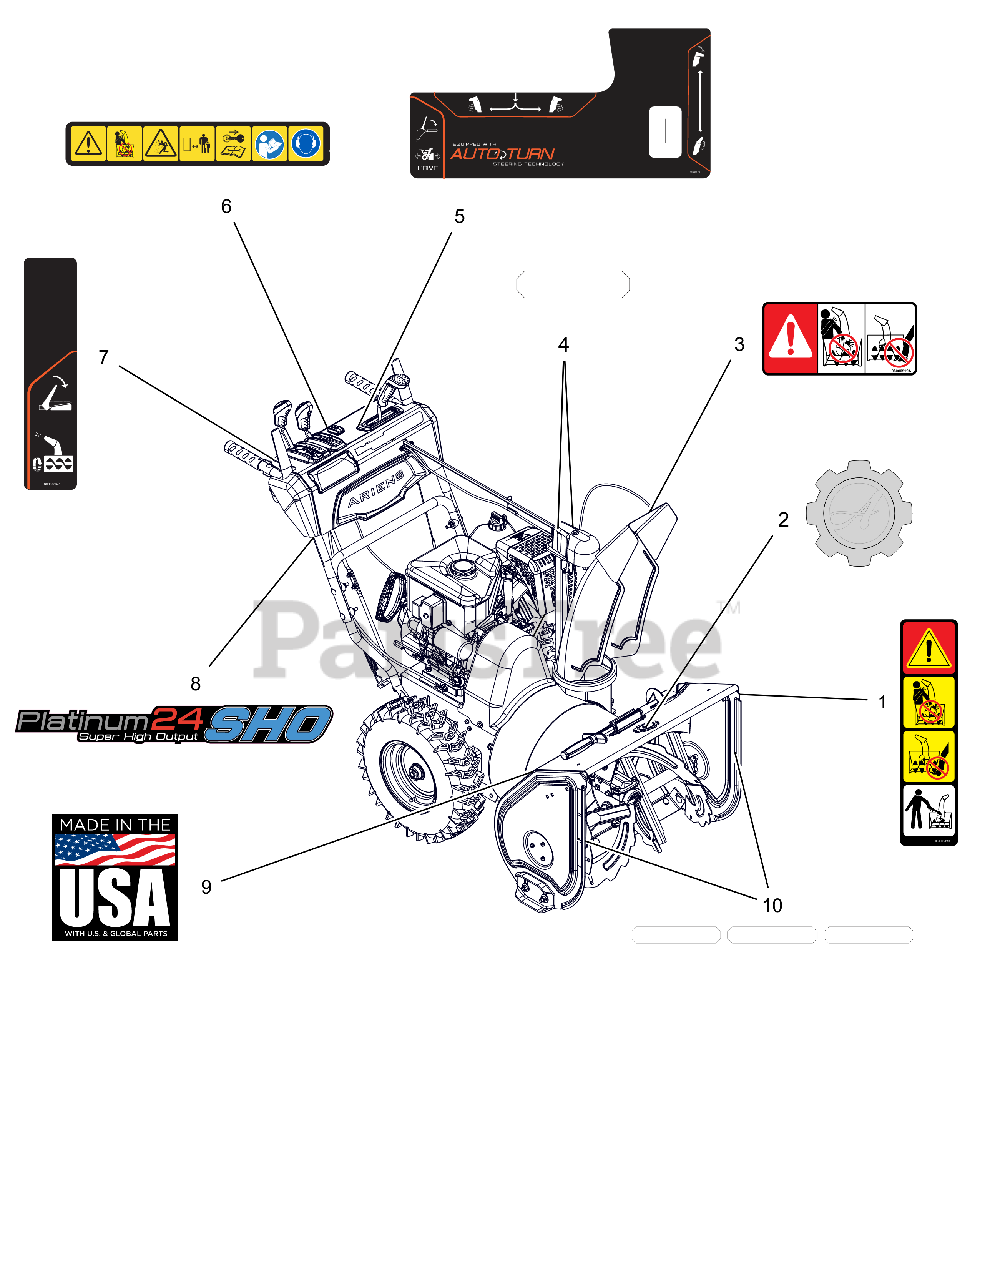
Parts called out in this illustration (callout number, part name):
1	DECAL, DANGER - ROTATING PARTS
2	DECAL, ARIENS-GEAR BADGE -THK
3	DECAL, DANGER
4	DECAL,REFLECTIVE,GEAR COVER
5	DECAL,CONTROL-LG QT2
6	DECAL,DASH - SAFETY
7	DECAL,CONTROL-RH CONTROL
8	DECAL, DASH, PLATINUM 24 SHO
9	DECAL, MADE IN USA
10	DECAL,REFLECTIVE,HOUSING
